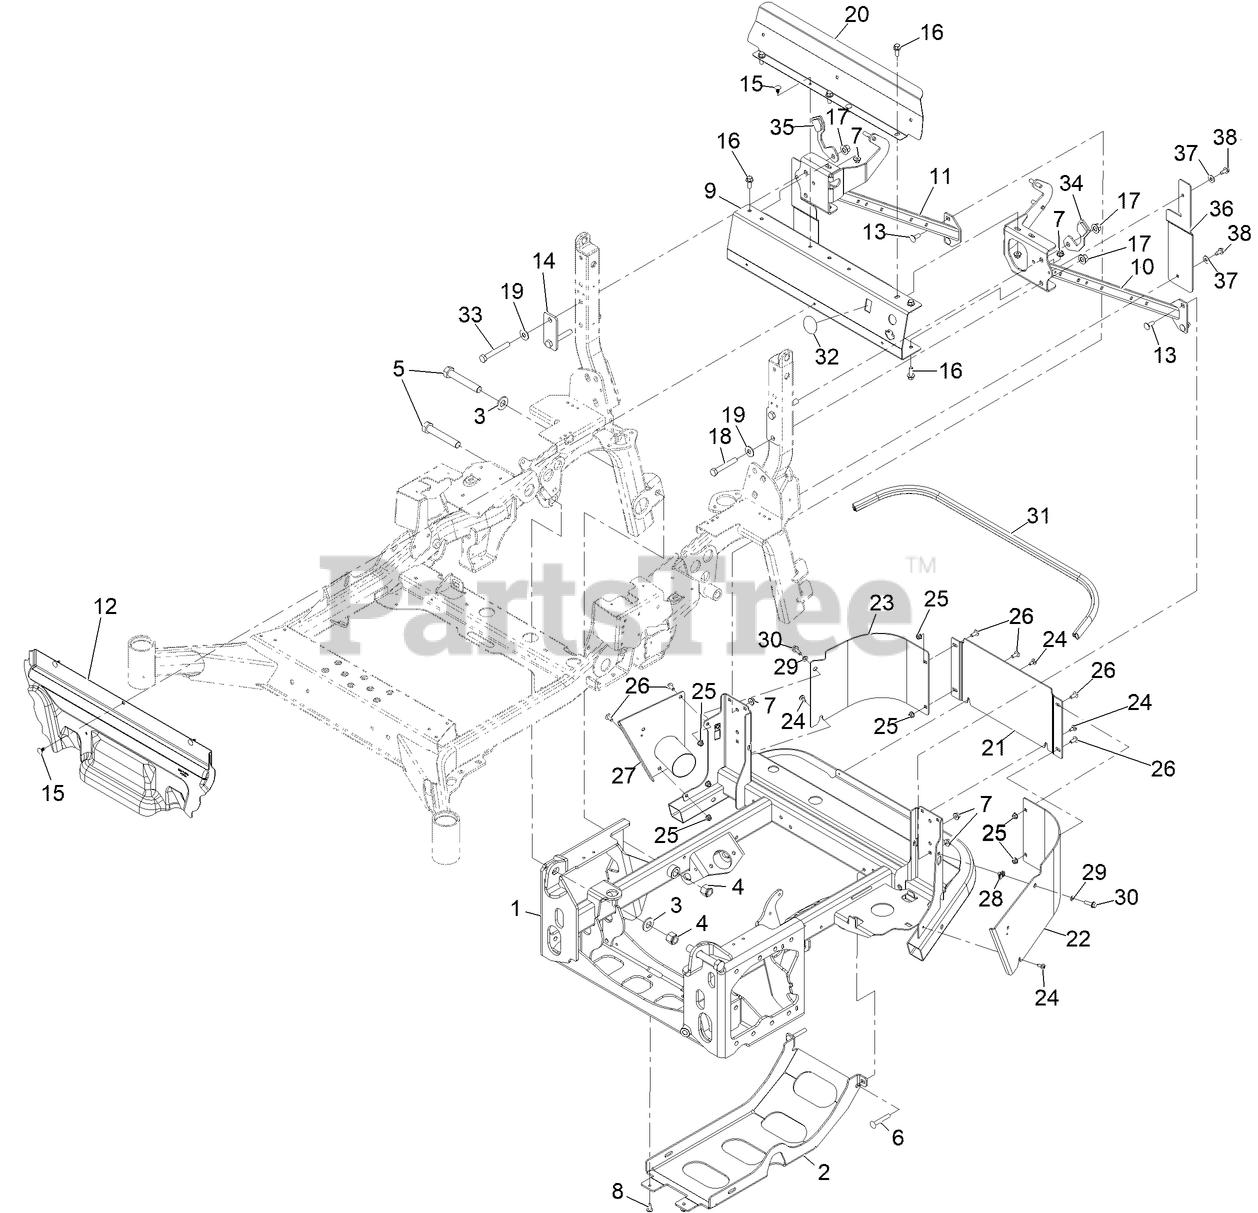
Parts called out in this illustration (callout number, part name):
1	FRAME-POWER
2	PLATE-SKID
3	WASHER
4	NUT-LOCK, NI
5	SCREW-HH
6	SCREW-CARR
7	NUT-HF, NI
9	CHANNEL-CROSS
10	WLDMT-ROPS LH BRACE
11	WLDMT-ROPS RH BRACE
12	PANEL-DEFLECTOR, HEAT
13	SCREW-CARR
14	PLATE-SPACER
15	PLUG-PLASTIC
16	SCREW-HHF
17	NUT-LOCK
18	SCREW-HH
19	WASHER-SPRING
20	SHIELD-AIR
21	PLATE-BUMPER, CENTER
22	PLATE-BUMPER, LH
23	PLATE-BUMPER, RH
24	SCREW-SHOULDER
25	NUT-HF, NI
26	SCREW-TORX
27	PLATE-EXHAUST
29	WASHER-BELLEVILLE
30	SCREW-HHF
31	SEAL-BULB
32	DECAL-COVER
33	SCREW-HH
34	STOP-ROPS [BLACK]
35	STOP-ROPS [BLACK]
36	SHEET-ROPS AIRDAM
37	WASHER-FLAT
38	SCREW-HWHTF
